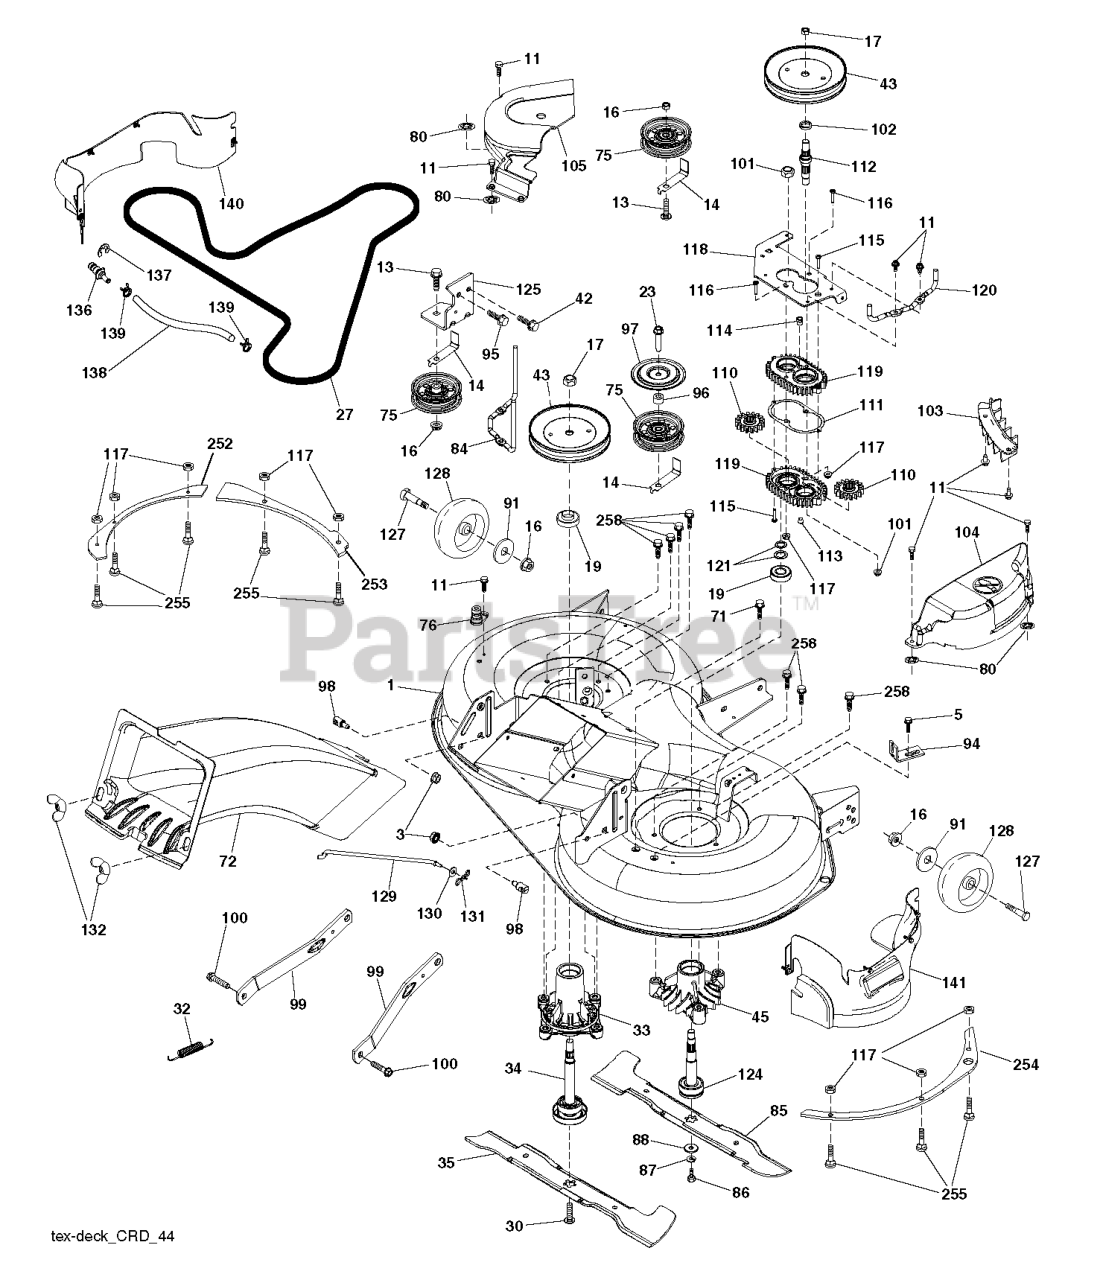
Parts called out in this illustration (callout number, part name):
1	DECK SVCX 97TXCRD 2GW 498
3	NUT LOCK HEX FLANGE 5/16-18
5	BOLT.5/16HEX.WHS.HD
11	SCREW.1/4-20X5/8
13	BOLT.3/8-16X1.50
14	KEEPER, BELT IDLER
16	NUT LOCK FLG 3/8-16 UNC
17	NUT.FLANGE.LOCK.TOP
19	BEARING.MANDREL.TOP.EXTENDED
23	SCREW LT
27	BELT 97CM ELECTRIC
30	SCREW.SEMS.7/16-20X1.HEX.HEAD
32	SPRING 107CM & 97CM ELECTRIC D
33	RP.HOUSING.MANDREL.4PT.
34	SHAFT ASM.MNDRL.N/GREASEABLE
35	BLADE.3N1.LH.CRD.97
42	SCREW
43	PULLEY.MANDREL.5.0.PD.38"
45	HOUSING.MANDREL.44/46" VENT
71	SCREW 3/8-16X1/2
72	CHUTE.TEX.CRD.GEN I.97 UPPER
75	FLAT IDLER PULLEY
76	1/2" BARB.DECK.WASHOUT.PORT
80	PALNUT 1/4
84	BELT KEEPER.MANDREL.38"COATED
85	BLADE.3N1.RH.CRD.97
86	BOLT.3/8-24X1.25GR8. LHTHRD
87	LOCKWASHER
88	WASHER.BLADE
91	WASHER
94	BRKT.CLUTCH.CABLE
95	SCREW, 3/8-16X3/4
96	SPACER
97	PROTECTOR
98	STUD.FASTNER.W/ANTI-ROTATE
99	ARM.SUSPENSION.MOWER.R
100	BOLT.SHOULDER
101	NUT.CROWNLOCK.9/16 -18.UNC
102	SPACER BEARING
103	GUARD GUARD FRONT VENT
104	97.CRD.RH.MANDREL.COVER
105	MANDREL MANDREL COVER LH
110	CRD.SPUR.GEAR
111	GASKET GASKET GEARCASE
112	SHAFT SHAFT. CRD GEARCASE ADAP
113	PLUG PLUG OIL
114	VENT.BREATHER.1/8 NPT
115	SCREW
116	BOLT.CARIGE.SS.1/4-20X1.75GR5
117	NUT T
118	ARM ARM CLUTCHING
119	GEARCASE GEARCASE SUBASM
120	BRACKET KEEPER BELT RH
121	WASHER WASHER
124	MANDREL SHAFT NON/GREASE
125	BRACKET BRACKET IDLER CHASSES
127	BOLT.SHOULDER.3/8-16X3-5/8.
128	RP WHEEL. GUAGE RALLY
129	ROD.ANTI.SWAY.48/54"K4
130	WASHER
131	PIN.COTTER.5/16.BOW TI
132	KNOB.HANDLE.3/8.TRI-POINT.BLAC
136	PLUG WASHOUT PORT HOOKUP
138	HOSE.3/8ID.BULK.12"
139	HOSE.3/8.CLAMP (2 2)
140	GUARD.ASSEMBLY.97.LH.FRENCH
141	GUARD.ASSEMBLY.97.RH.FRENCH
252	PLATE.REINFORCEMENT.LHS.X431
253	PLATE.REINFORCEMENT.LHS.X431
254	PLATE.REINFORCEMENT.X431
255	RHSNB, 1/4-20 X 1, GR5
258	BOLT.HEX.WASHR.HED.313-18X1.19
